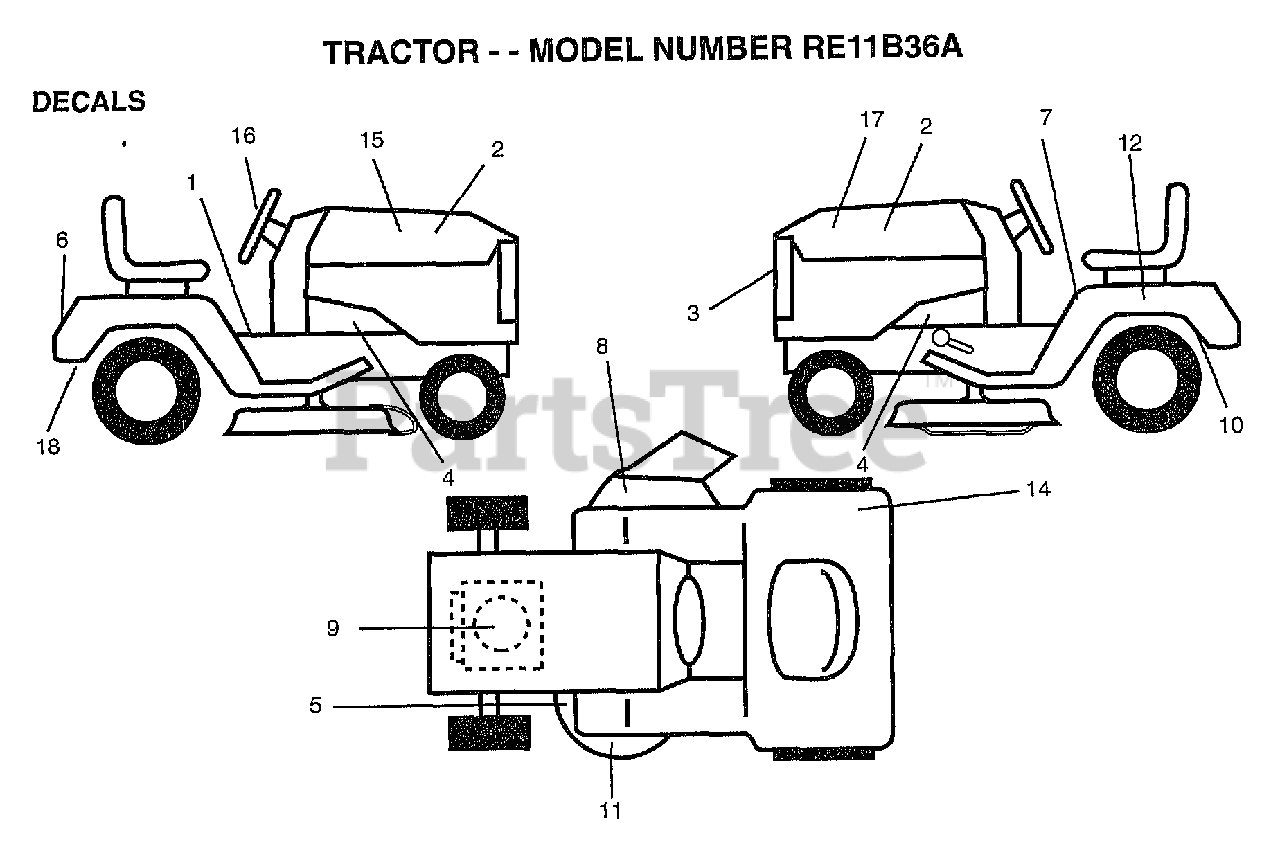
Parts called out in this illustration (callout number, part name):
1	DECAL CLUTCH/BRAK
2	DECAL.HOOD.INSERT
3	GRILL DECAL
4	"DECAL CHASSIS,HOT"
5	DECAL.V.BELT
6	FENDER DECAL
7	DECAL.READ.O.MANU
8	DECAL.DANGER.CUTF
10	DECAL.DRAWBAR.LDL
12	DECAL.BATRY.3-3908
15	DECAL HD RLY RH
16	"DECAL,STR WHL"
17	DECAL HD RLY LH
18	DECAL.EURO.ST.CE.
